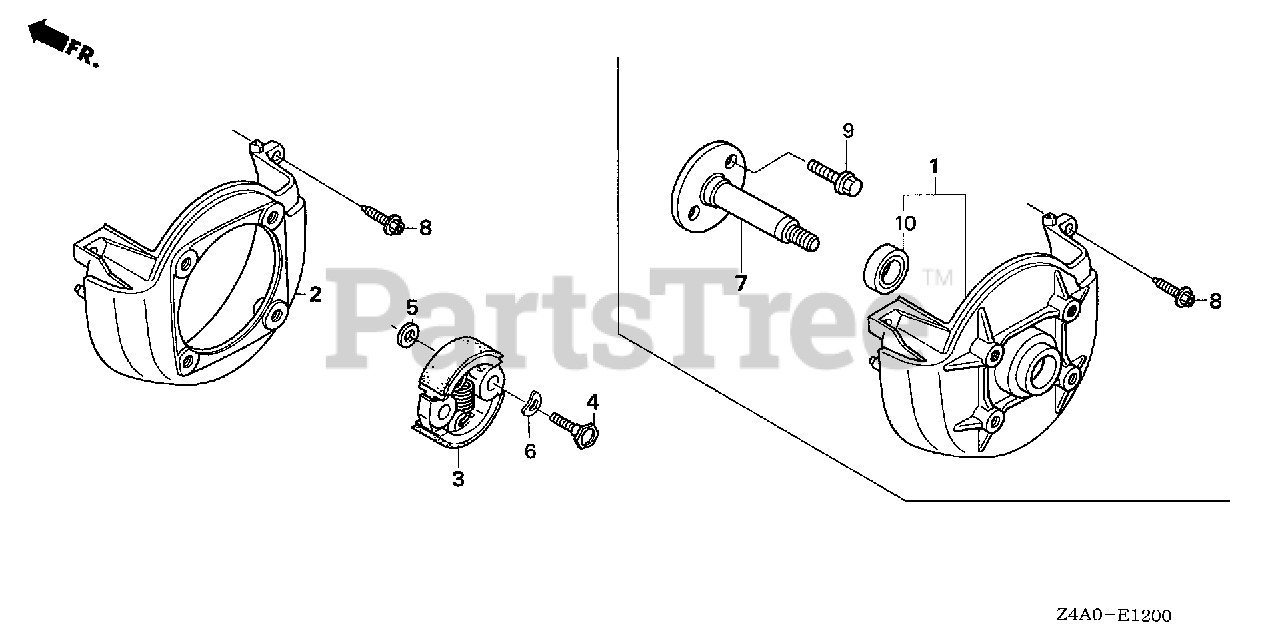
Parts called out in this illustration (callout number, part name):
2	COVER, FAN
3	CLUTCH ASSY.
4	BOLT, CLUTCH (6MM)
5	WASHER, CLUTCH (6X16.5)
6	WASHER, WAVE (8.2X16)
8	BOLT, SOCKET (5X20)
